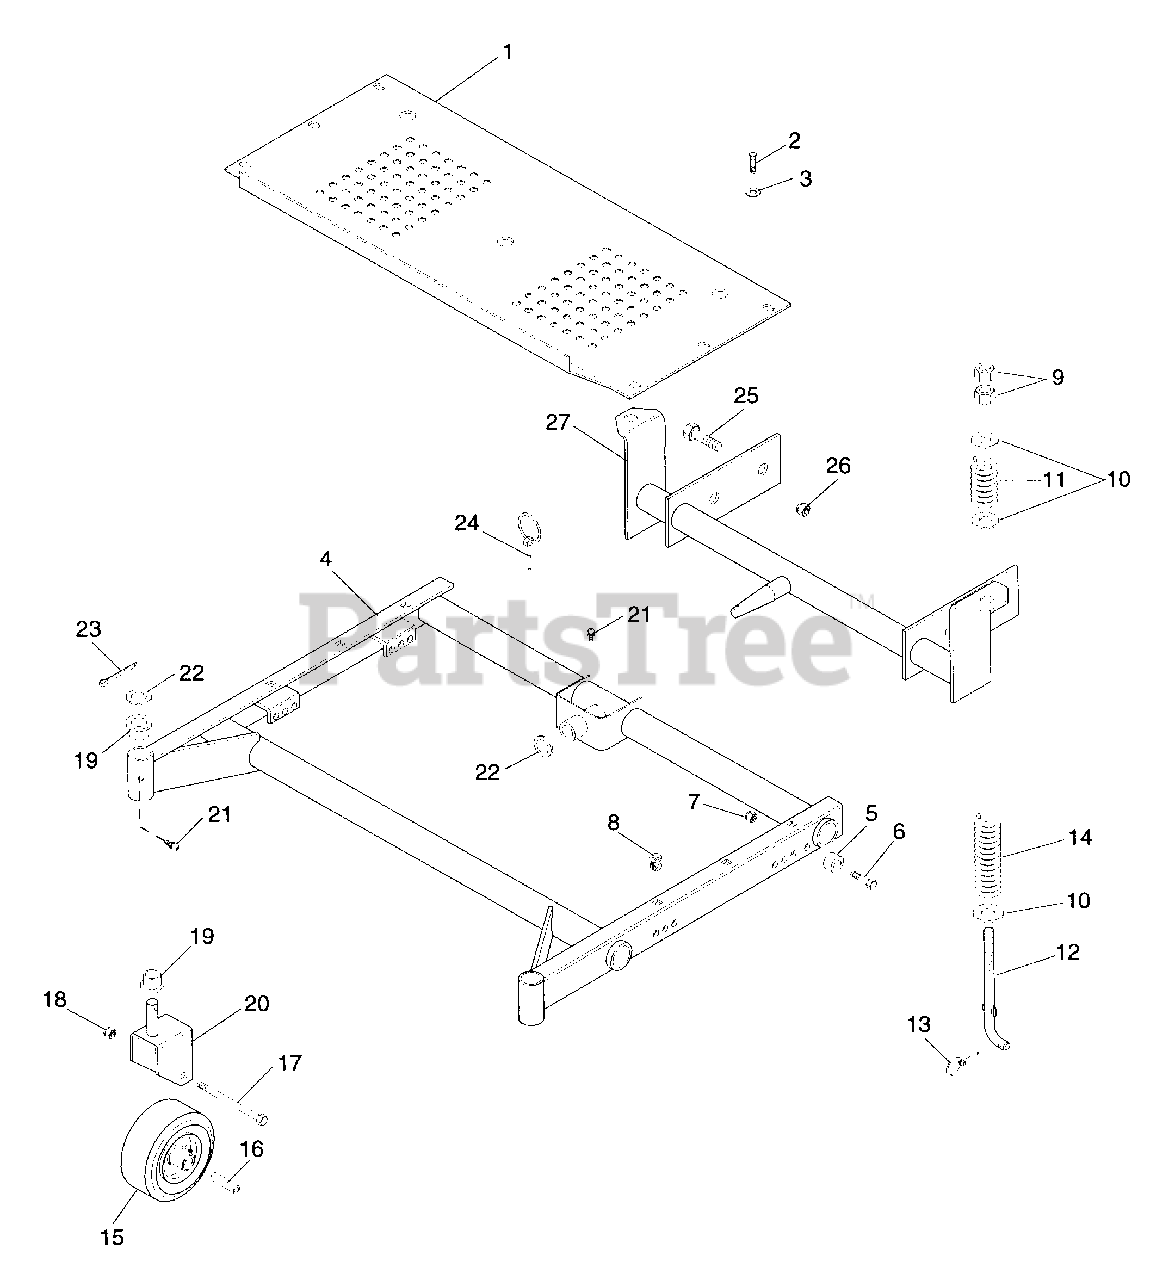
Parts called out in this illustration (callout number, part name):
1	Footboard
2	Scr-Mch .25-20 Pan Hd
3	Wshr-Fl-Stl .281 x .625 x .065
4	Wldmt, Mwr Frame 40" 3 Spndl
5	Bush., 021076 W/E - Coat Finish
6	Blt-Hex .38 - 16 x 1.50 Pl Gr 5
7	Nut-Lk-Nyl .375 - 16 Pl
8	Clip, U - Type Eaton #C17453-1420
9	Nut, 50 - 13 Pl
10	Wshr-FI-Stl .531 x 1.062 x .095
11	Spring-Compression .125 x .78 x 1.00
12	Rod, Height Adj.
13	Pin-Klik 1.000 x .188 x 1.25
14	Sg.-Comp .095 x .75 x 6.25 Wld 35
15	Whl, Ga 11 x 4 - 4
16	Bush., Caster Fork
17	Blt-Hex .50 - 13 x 6.50
18	Nut-Lk-Nyl .50 - 13 Pl
19	Bshg-Flg 1.020 x 1.75 x .75 Nyl
20	Wldmt, Caster Fork
21	Ftg, Lube, .25 - 28 Self-Thread
22	Brg-R-Thrst 1.002 x 1.552 x .030
23	Pin-Cotr .12 x 1.25 Pl
24	Pin-Klik .25 x 1.75
25	Blt-Hex .625 - 11 x 1.50
26	Nut, Lk 5/8 - 11 Hex W/Insr
27	Wldmt, Mwr Frame Mtg
